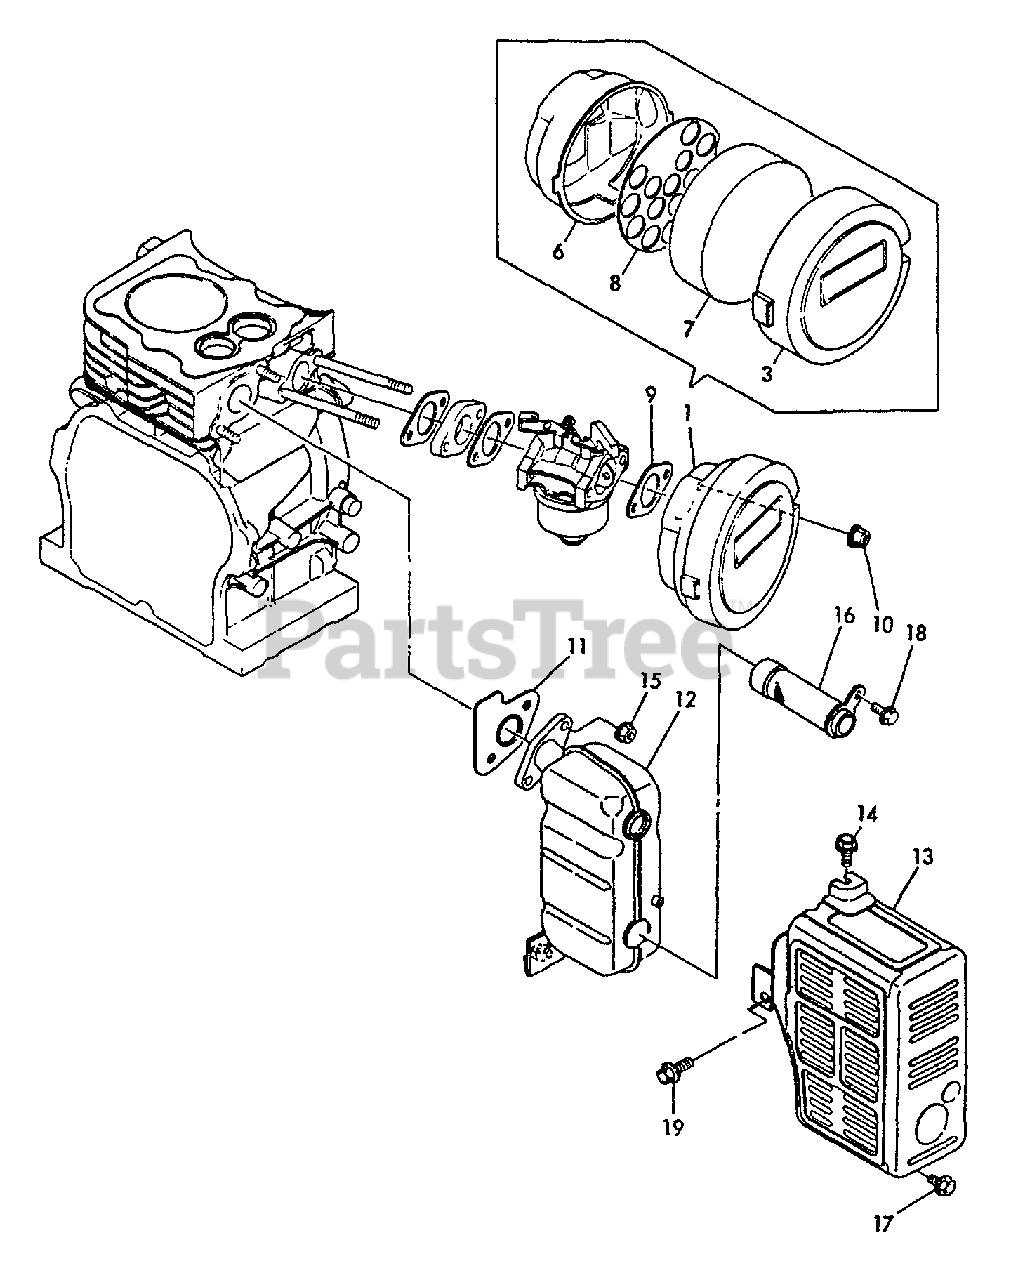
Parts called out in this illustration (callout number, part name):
1	AIR CLEANER ASSY
3	COVER, AIR FILTER
6	CASE, AIR FILTER
7	FILTER, AIR
8	RETAINER, AIR FILTER
9	GASKET, INTAKE
10	NUT - 6 -- FLANGE
11	GASKET, EXHAUST
12	MUFFLER
13	COVER, MUFFLER
14	BOLT - 6X8 -- PLATED
15	NUT - 6 -- FLANGE
16	SCREEN, SPARK ARRESTOR
17	BOLT - 6X8 -- PLATED
18	BOLT - 6X10 -- PLATED
19	BOLT - 8X14 -- PLATED
